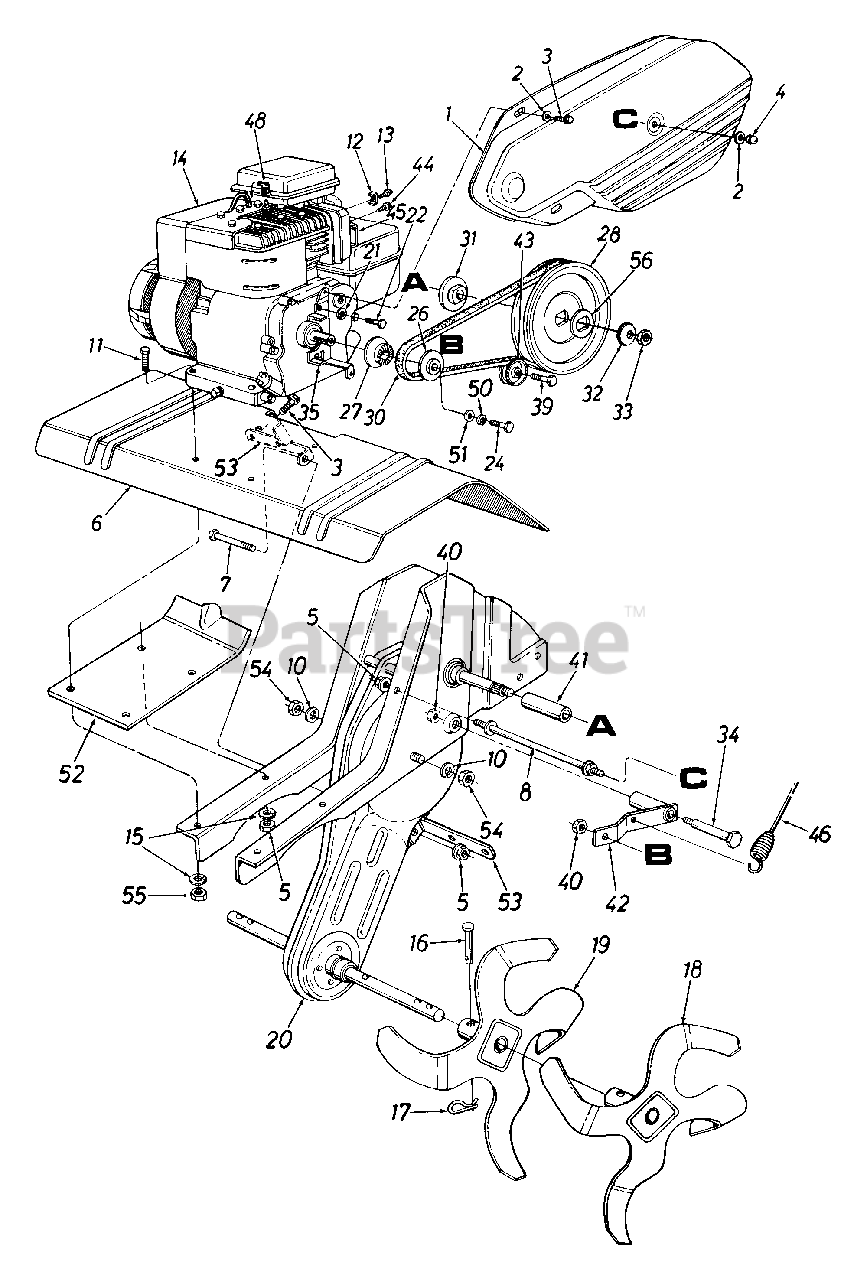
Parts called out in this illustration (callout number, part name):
2	Fl-Wash. .266" I.D. x .625" O.D.
3	Hex Wash. Hd. TT-Tap Scr. 1/4-20 x .5" Lg.
4	Hex L-Stop Nut 1/4-28 Thd.
5	Hex Flange Top L-Nut 5/16-18 Thd. (Gr. 5)
8	Belt Cover Bolt
10	L-Wash. 7/16" I.D.
11	Hex Bolt 5/16-18 x 1.75" Lg.
12	Casing Clamp
13	Hex Sems Scr. #10-32 x .62" Lg.
14	Engine
15	Spec. L-Nut 5/16" I.D.
16	Clevis Pin .375" Dia. x 1.75" Lg.
17	Internal Cotter Pin
18	Outer Tine Ass'y. - L.H.
19	Inner Tine Ass'y. - L.H.
20	Chain Case Ass'y. Comp.
21	L-Wash. 5/16" I.D.
22	Hex Bolt 5/16-24 x .5" Lg.
24	Hex Bolt 3/8-24 x 1.25" Lg.
26	Outer Engine Pulley Half
27	Inner Engine Pulley Half
28	Fl-Pulley 6" Dia.
30	V - Belt
31	Pulley Mounting Adapter
32	Bell - Wash..535" I.D. x 1.5" O.D.
33	Hex Jam Nut 1/2-20 Thd. (Gr. 5)
34	Shld. Bolt .498" Dia. x 1.45" Lg.
35	Belt Cover Brkt.
38	Fl-Idler 2.12" O.D.
39	Hex Cap Bolt 3/8-16 x 1.25" Lg.
40	Hex Cent. Jam Nut 3/8-16 Thd.
41	Spacer .64" I.D. x 2.4" Lg.
42	Tine Idler Brkt. Ass'y.
43	Fl-Idler 2" O.D.
44	Hex Self - Tap Scr. #8-32 x .38" Lg.
45	Muffler Deflector
46	Clutch Control Cable
48	Spark Plug Boot
50	L-Wash. 3/8" I.D.
51	Fl-Wash. 3/8" I.D. x 1" O.D.
54	Hex Nut 7/16-20 Thd.
55	Hex Nut 5/16-18 Thd.
56	Bearing Retainer Washer
